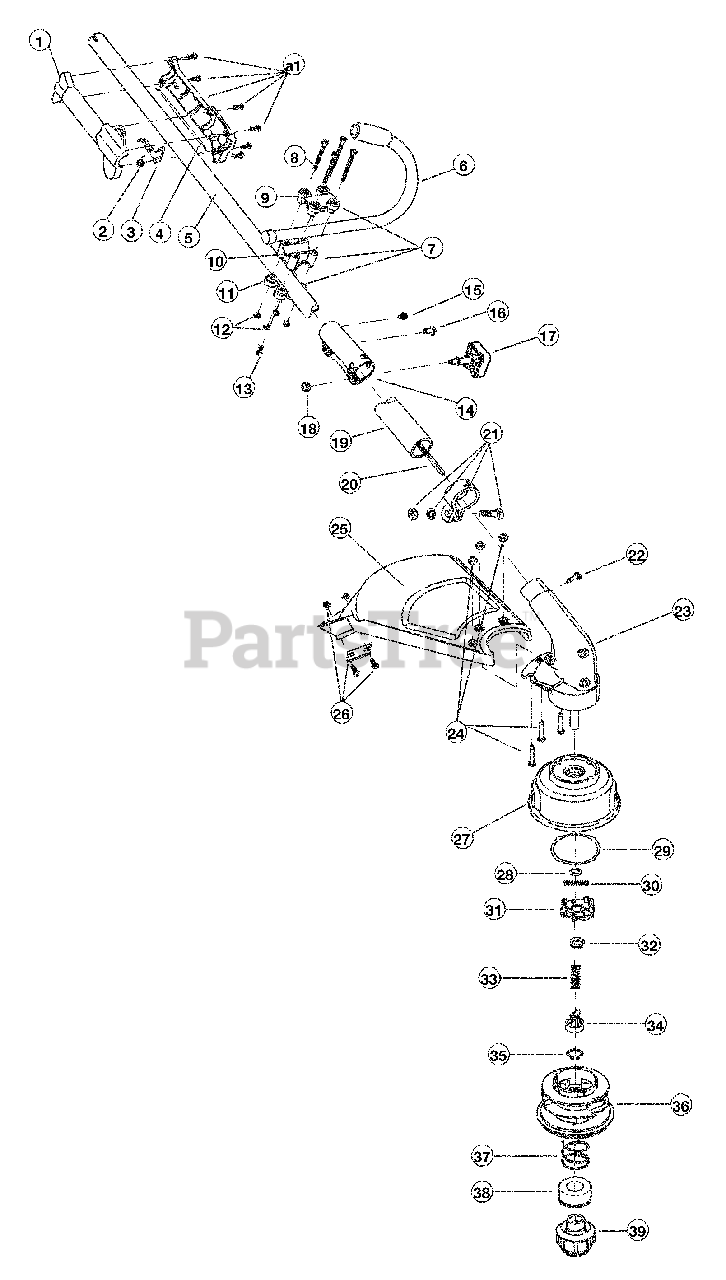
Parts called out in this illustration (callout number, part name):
1	Throttle Housing & Trigger Assembly
2	Throttle Trigger Spring
3	Throttle Trigger
4	Throttle Cable Assembly
5	Upper Drive Shaft Housing Assembly
6	J-Handle Assembly
7	Handle Bracket Assembly
9	Upper Handle Clamp
10	Middle Handle Clamp
11	Lower Handle Clamp
13	Anti-Rotation Screw
14	Split Boom Coupler
17	Adjustment Knob
18	Knob Retaining Nut
19	Lower Drive Shaft Housing Assembly
20	Lower Flexible Drive Shaft
21	Lower Clamp Assembly
22	Anti-Rotation Screw
23	Gearbox Assembly
24	Shield Mounting Hardware
25	Shield and Blade Assembly
26	Blade Assembly
27	Outer Spool Assembly
28	Retainer
29	Thrust Washer
30	Small Spring
31	Slider
34	Plunger
36	Inner Reel
37	Large Spring
38	Foam Seal
39	Bump Knob Assembly
